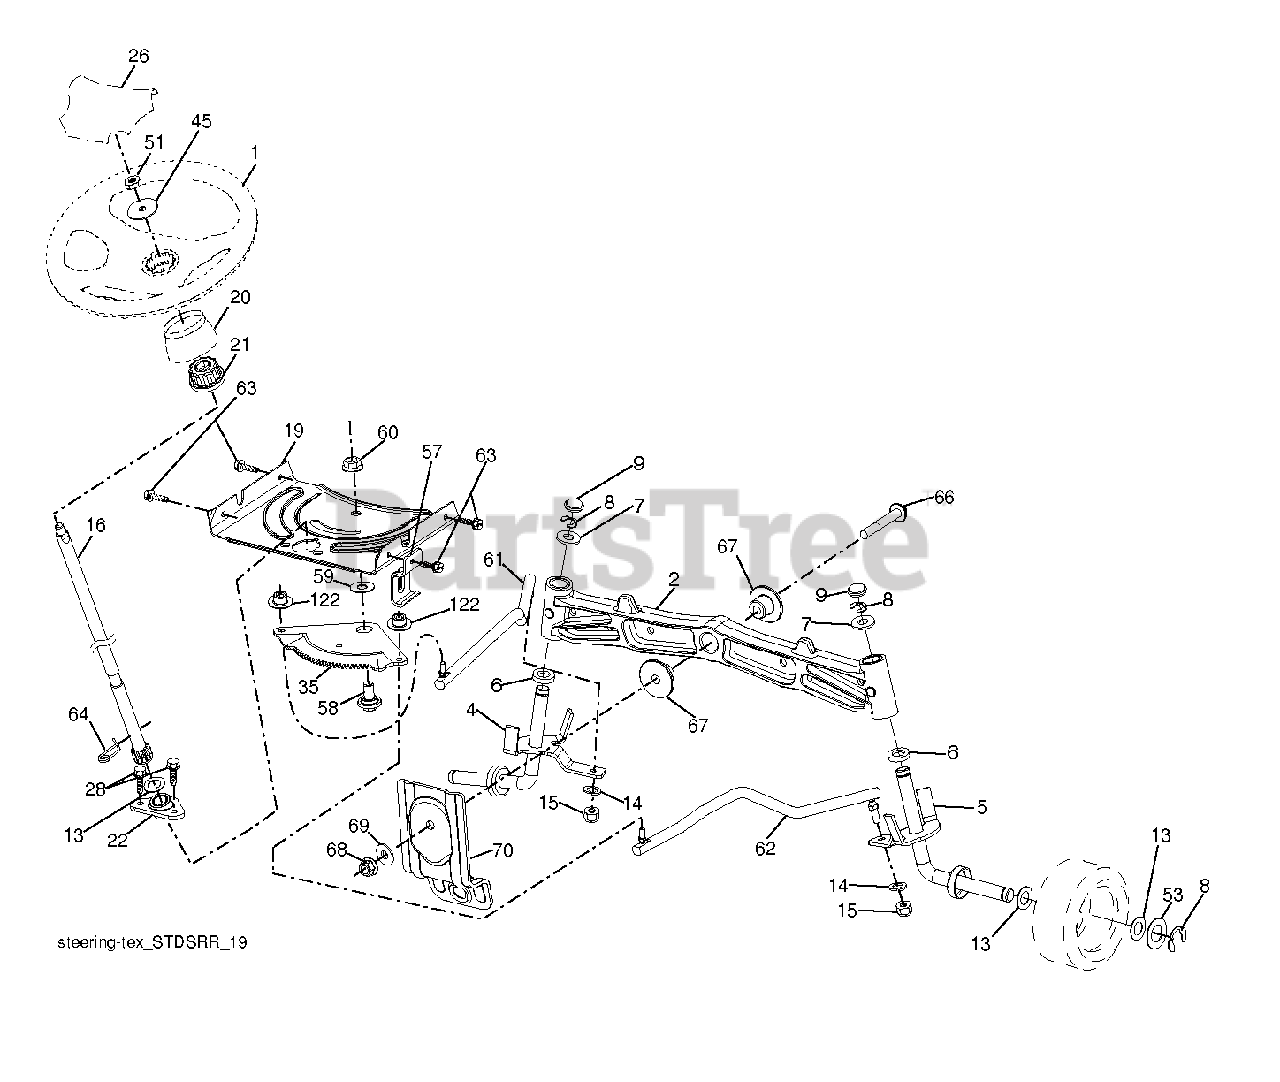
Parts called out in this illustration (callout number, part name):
1	WHEEL, STEERING
4	SPINDLE.WELDED.LH.15"T
5	SPINDLE.WELDED.RH.15"T
6	BRNG T
14	WASHER, LOCK 3/8
15	NUT CROWNLOCK 3/8-24
19	PLATE.STEER.DDL.NLT/NG
20	BOOT.STEERING.
21	ADAPTER, WHEEL STNG
22	STEERING.SUPT.LOWER.
26	INSERT, WHEEL STEERING
28	SCREW, 3/8-16X3/4
35	GEAR.SECTOR.PLATE.DDL.
57	BRKT.UPSTOP.GT/LT.TEX
58	BOLT.SHOULDER.SECTOR.P
59	WASHER.THURST.SECTOR.S
60	NUT FLANGE LOCK 5/8-11
61	DRAGLINK.LH.BALLSTUD.D
62	DRAGLINK.RH.BALLSTUD.D
63	SCREW
64	RETAINER.CLIP.SPRING.S
66	BOLT HEX FGHD 7/16-14 X 3 SERR
67	BUSHING.PM.FRONT AXLE
68	NUT.LOCK.FLANGE.7/16
69	WASHER.1.5X.505X.118
70	BRKT.DECK.SUSPENSION.F
